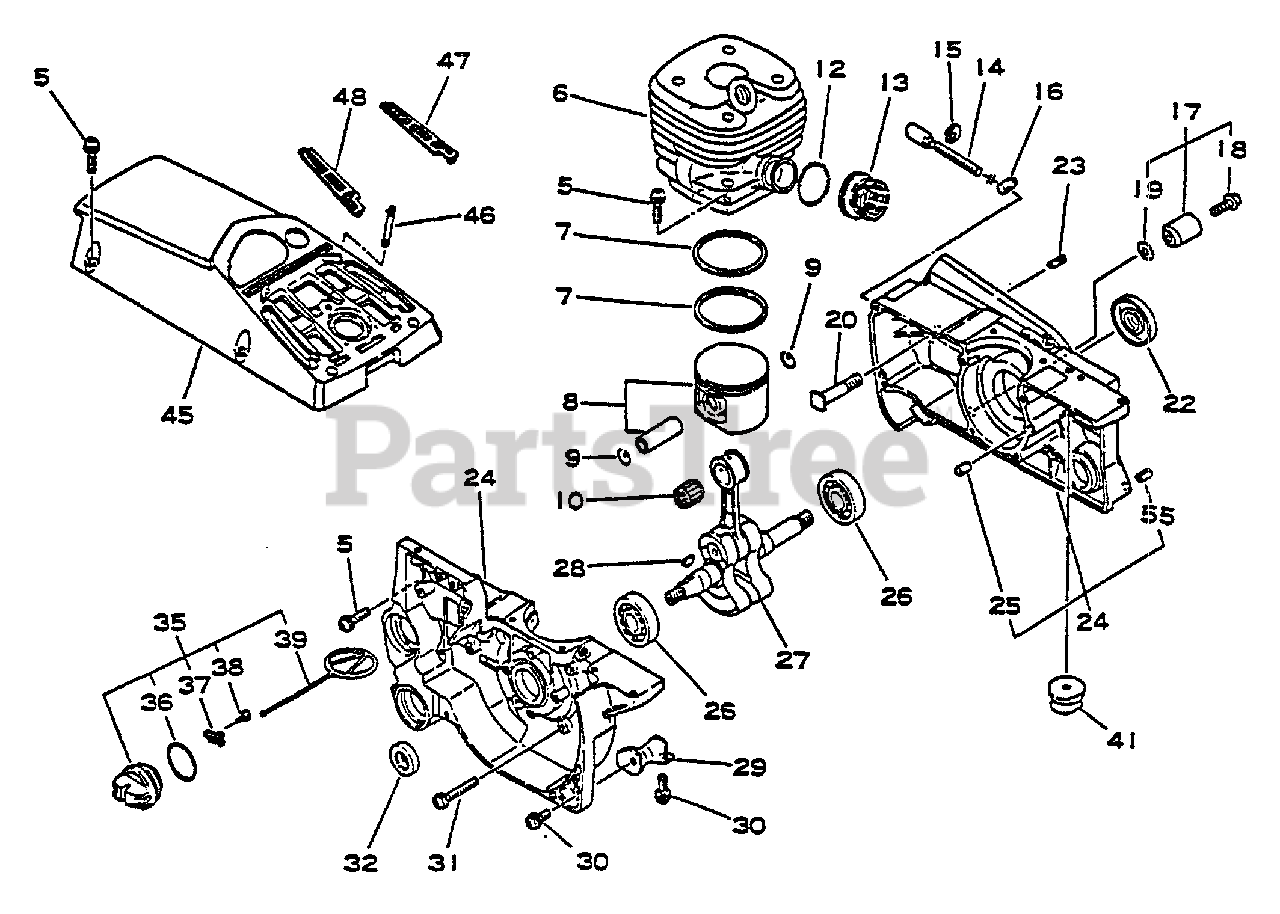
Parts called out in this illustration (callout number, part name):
5	SCREW - 5X20
6	CYLINDER KIT
7	RING, PISTON
8	PISTON KIT
9	RING, RETAINING
10	BEARING, NEEDLE
13	BELLOWS, INTAKE
14	SCREW, TENSIONER
16	TENSIONER, CHAIN
17	CHAIN CATCHER KIT
18	SCREW - 5X20
19	WASHER - 5
20	STUD, GUIDE BAR
22	SEAL, OIL
23	VENT, TANK
24	CRANKCASE KIT - GRAY
25	PIN - LOCATING
26	BEARING SET
27	CRANKSHAFT ASSY
30	SCREW - 5X14
31	SCREW - 5X35
32	SEAL, OIL
35	CAP ASSY
37	RETAINER
38	SCREW - 3X8
39	CONNECTOR, CAP
41	CUSHION - A
45	COVER, ENGINE - GRAY
47	DEBRIS FILTER KIT
48	FILTER, AIR
55	PIN - SPRING -- 5X10
